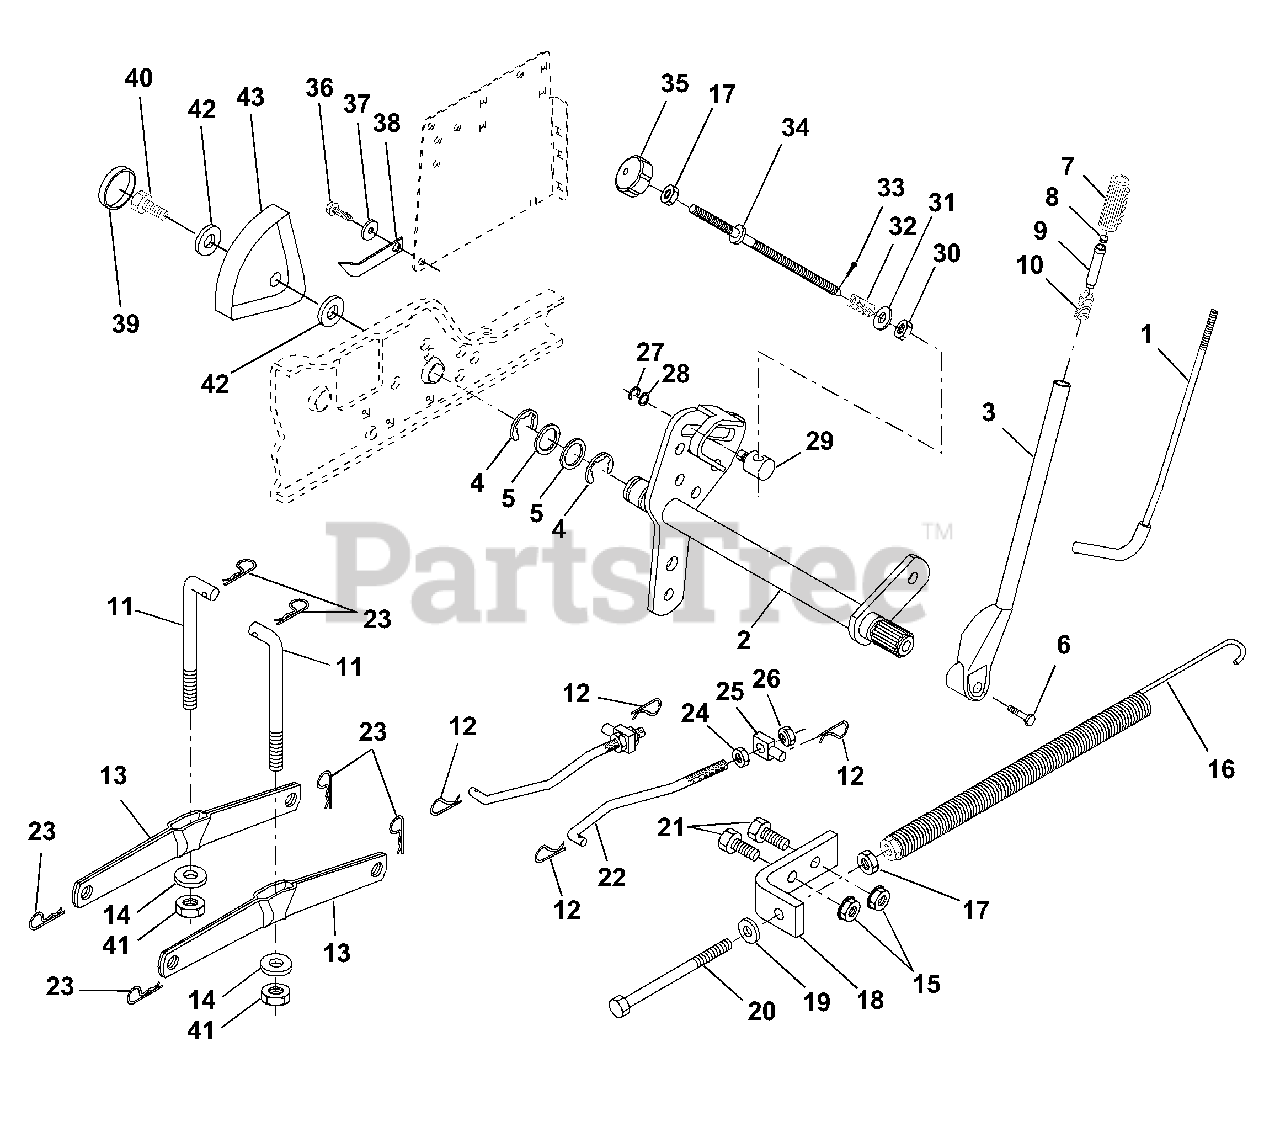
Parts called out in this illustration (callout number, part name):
1	Rod Asm., Lever
2	Shaft Asm., Lift Vgt
3	Lever Asm., Lift Rh
4	E-Ring Truarc #5133-87
5	Washer 29/32 x 1-1/4 x 16 Ga.
6	Bolt, Fin Hex 3/8-16 x 1-1/2
7	Grip, Handle Fluted
8	Button, Plunger
9	Plunger, Lever Lift
10	Spring 2-1/8"
11	Link Lift
12	Retainer, Spring
13	Arm, Suspension Vgt
14	Bearing
15	Nut, Lock Hex W/Wsh 3/8-16 Unc
16	Spring Asm., Assist Lift
17	Nut, Hex Jam 3/8-16 Unc
18	Bracket, Spring Assist
19	Washer 13/32 x 13/16 x 16 Ga.
20	Bolt, Adjust Spring Assist
21	Bolt, Fin Hex 3/8-16 x 1
22	Link, Front
23	Retainer, Spring
24	Nut, Jam Hex 1/2-13 Unc
25	Trunnion
26	Nut, Lock W/Wsh 1/2-13 Unc
27	Ring, Klip #T5304-37
28	Washer 15/32 x 3/4 x 16 Ga.
29	Trunnion, Dp Stop Dbl Thds Plt
30	Nut, Special
31	Washer 13/32 x 5/8 x 16 Ga.
32	Spring, Compression Inf Hgt
33	Pin, Cotter 3/32 x 1/2
34	Rod, Adj Lift
35	Knob, Inf 3/8-16 Unc
36	Screw, Thdrol 3/8-16 x 3/4
37	Washer, Nylon
38	Pointer, Pnt Height Indicator
39	Plug, Hole
40	Screw Thdrol 5/16-18 x 3/4
41	Nut, Crownlock 3/8-24
42	Washer 11/32 x 1-1/2 x 10 Ga.
43	Scale, Indicator Height
